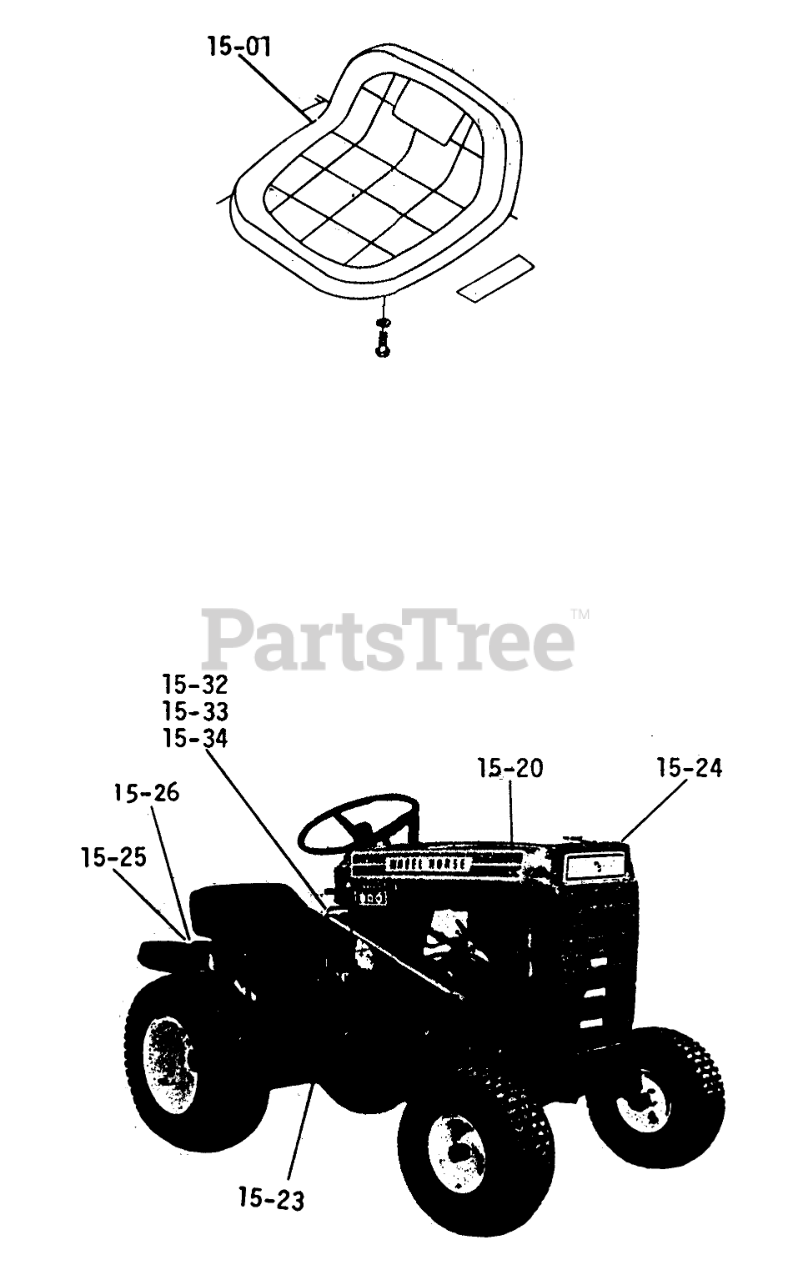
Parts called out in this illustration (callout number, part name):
15	Shifter Ball
15	Decal
15	DECAL-4 SPD SHIFT
15	DECAL-HAND LIFT
15-01	Seat
15-20	Decal-Hood
15-23	Decal--Commando 800-3 Speed
15-25	Decal
15-26	Reflector
15-32	Deal-Seat Latch
15-33	Decal-Shift Pattern
15-34	Decal-Caution (lower hoodstand)
